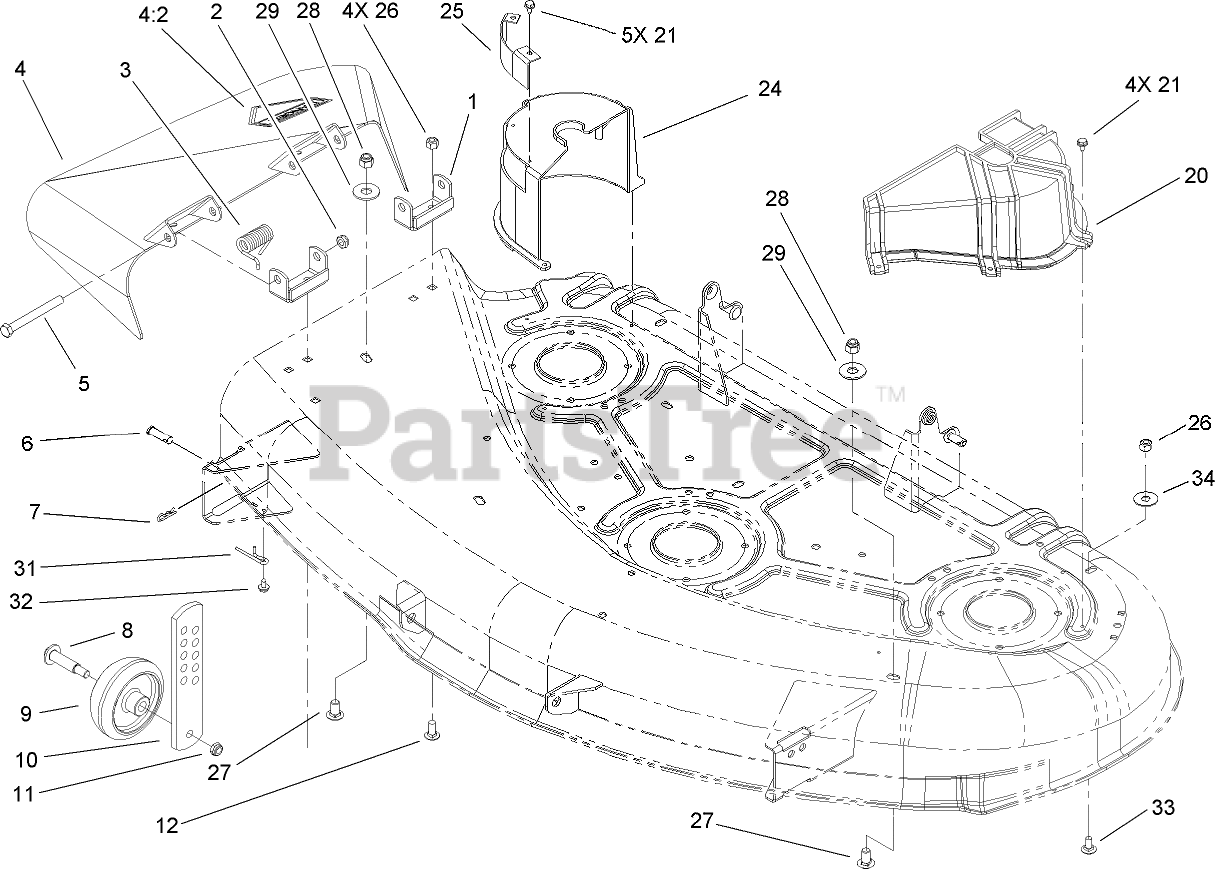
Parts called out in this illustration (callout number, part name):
1	BRACKET-PIVOT
2	NUT-HEX
3	SPRING
4	DEFLECTOR ASM
4:2	DECAL-DANGER
5	SCREW-HH
6	PIN-CLEVIS
7	PIN-COTTER
8	SCREW-SHOULDER, HWH
9	WHEEL-GAGE
10	PLATE-GAGE, WHEEL
11	NUT-LOCK, NI
12	SCREW-CARR
20	COVER-BELT, LH
21	SCREW-HWHTF
24	COVER-BELT, RH
25	INSERT-BELT COVER
26	NUT-LOCK, NI
27	SCREW-CARR
28	NUT-LOCK, NI
29	WASHER-FLAT
31	SPRING-GAGE, WHEEL
32	SCREW-HWHTF
33	SCREW-CARR
34	WASHER
